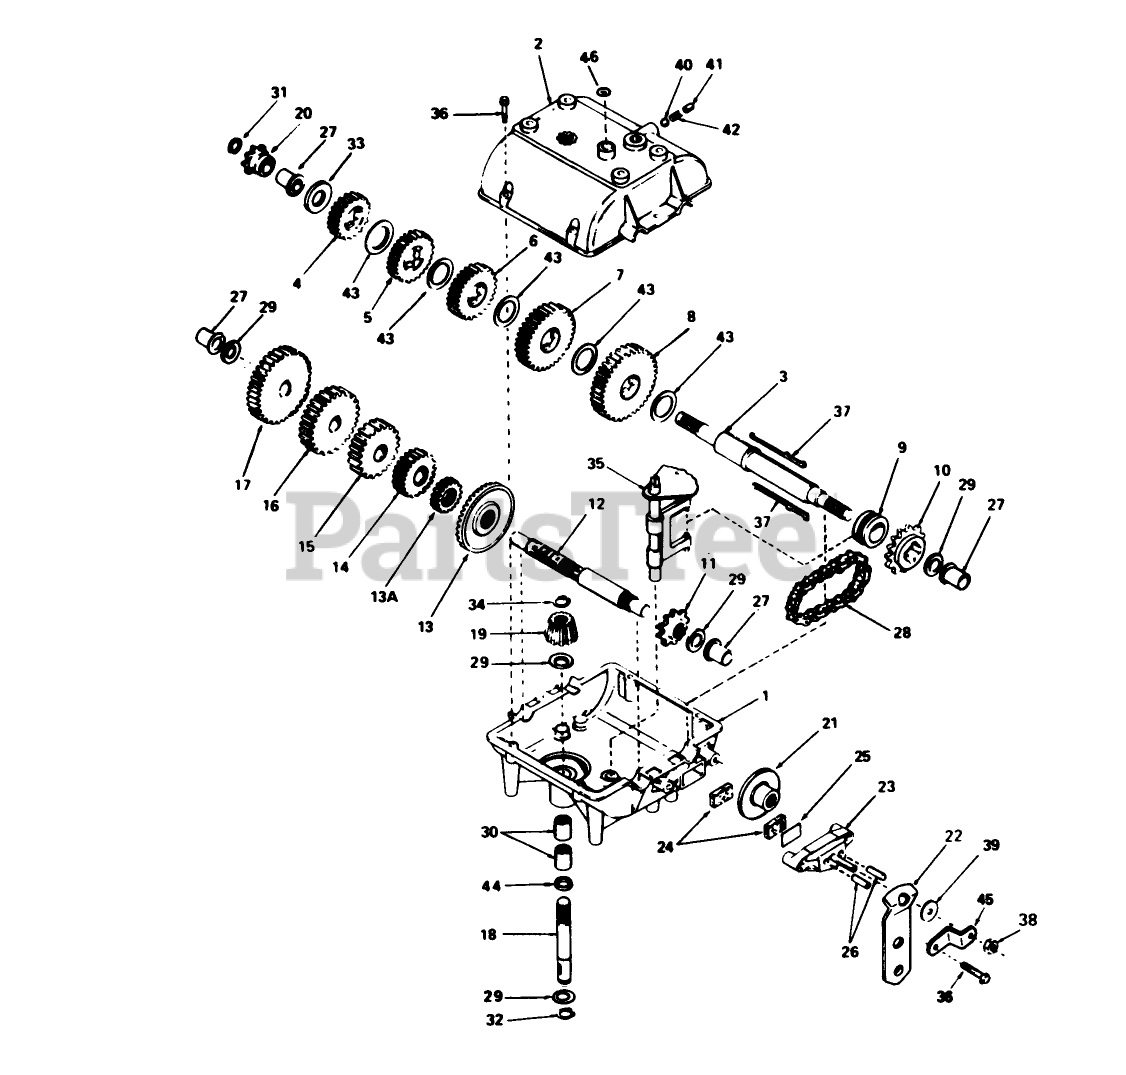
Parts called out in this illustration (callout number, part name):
1	Case-Transmission
2	Cover-Transmission
3	Shaft-Output
4	Gear-Spur 20 teeth
5	Gear-Spur (22 teeth)
6	Gear-Spur, 25 Teeth
7	Gear-Spur, 30 Teeth
8	Gear-Spur, 35 Teeth
9	Collar-Shift
10	Sprocket-18 Teeth
11	Sprocket-9 Teeth
12	Countershaft
13	Gear-Bevel (42 Teeth)
13A	Gear-Spur 15 Teeth
14	Gear-Spur, 20 Teeth
15	Gear-Spur, 25 Teeth
16	Gear-Spur (28 teeth)
17	Gear-Spur (30 teeth)
18	Shaft-Input
19	Bevel Pinion-Input
20	Sprocket (8Teeth)
22	Lever-Brake
23	Nozzle-Carburetor
24	Brake Pad
25	Brake Pad Plate
26	Dowel Pin
27	Bushing-Flange
28	Chain-Roller #41
29	Washer
30	Bearing-Needle
31	Piston Asm (.020 O S)
32	Ring-Snap
33	Washer
34	Ring-Retainer
35	Rod and Fork ASM
36	Ring Set (.020 O S)
38	Locknut
39	Washer
40	Ball-Steel
41	Screw-Set
42	Spring
43	Washer
44	O Ring
45	Bracket
46	Cut Seal-Square
